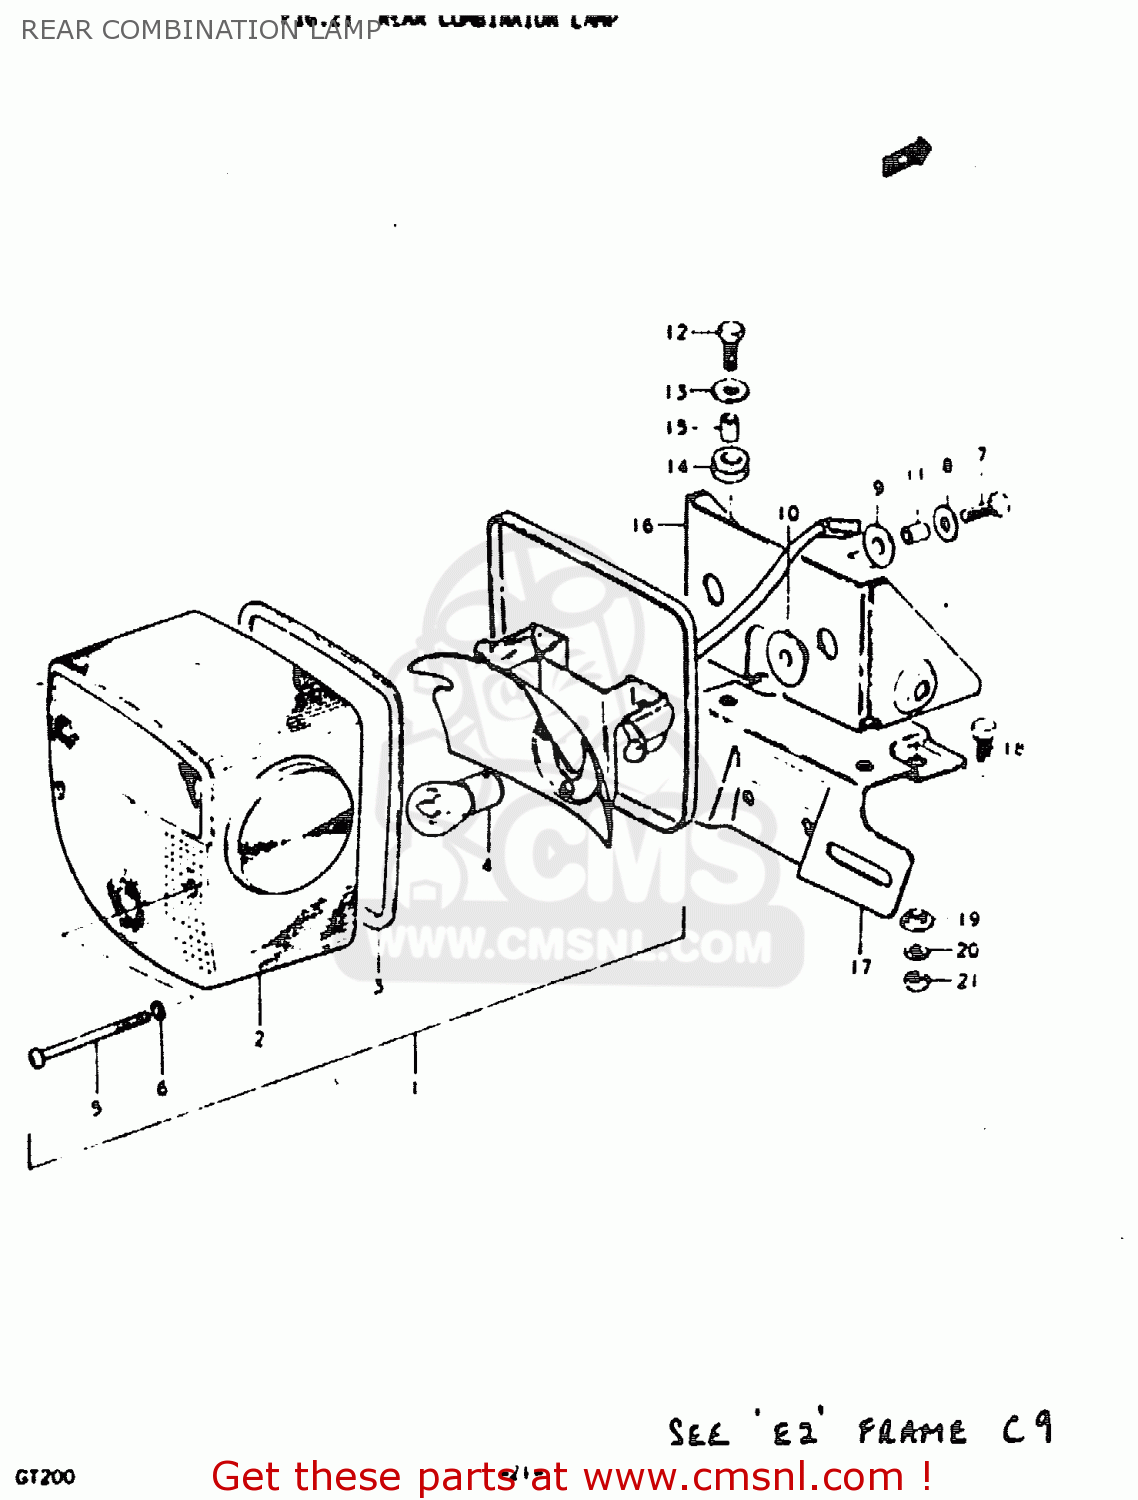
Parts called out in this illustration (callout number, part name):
1	LAMP ASSY, REAR COMBINATION
2	LENS
3	GASKET (NAS)
4	BULB(12V23W)
5	SCREW (4X55)
6	GASKET (NAS)
7	BOLT
8	WASHER (6.5X20X1.2)
9	CUSHION
10	CUSHION
11	SPACER (6.8X10X11.5)
12	BOLT, UPPER
13	WASHER (6.5X20X1.2)
14	CUSHION
15	SPACER (6.1X9X9)
16	BRACKET, COMBINATION LAMP
17	PLATE, LICENSE
18	BOLT
19	SPACER
20	LOCK WASHER
21	NUT
